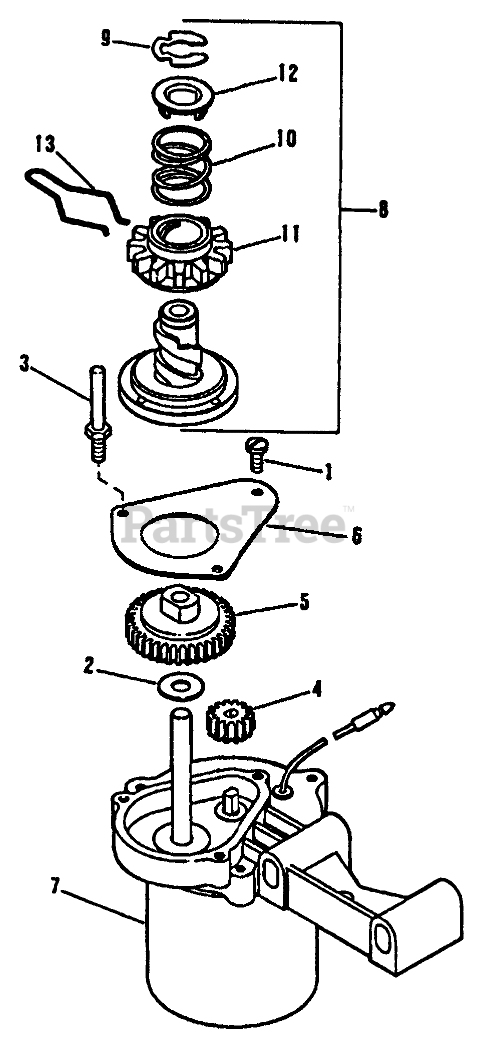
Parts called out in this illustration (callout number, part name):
1	SCREW EF
2	Washer
3	STUD,DRAG SPR. E
4	PINION SM
5	GEAR - DRIVEN SM
6	GEAR COVER EF
7	Assy.-Housing & Pin
8	PIN,SPR CLUTCH SM
9	RET.RING EF
10	SPRING PINION EF
11	PINION SM
12	STOP WASHER EF
13	SPRING - DRAG
